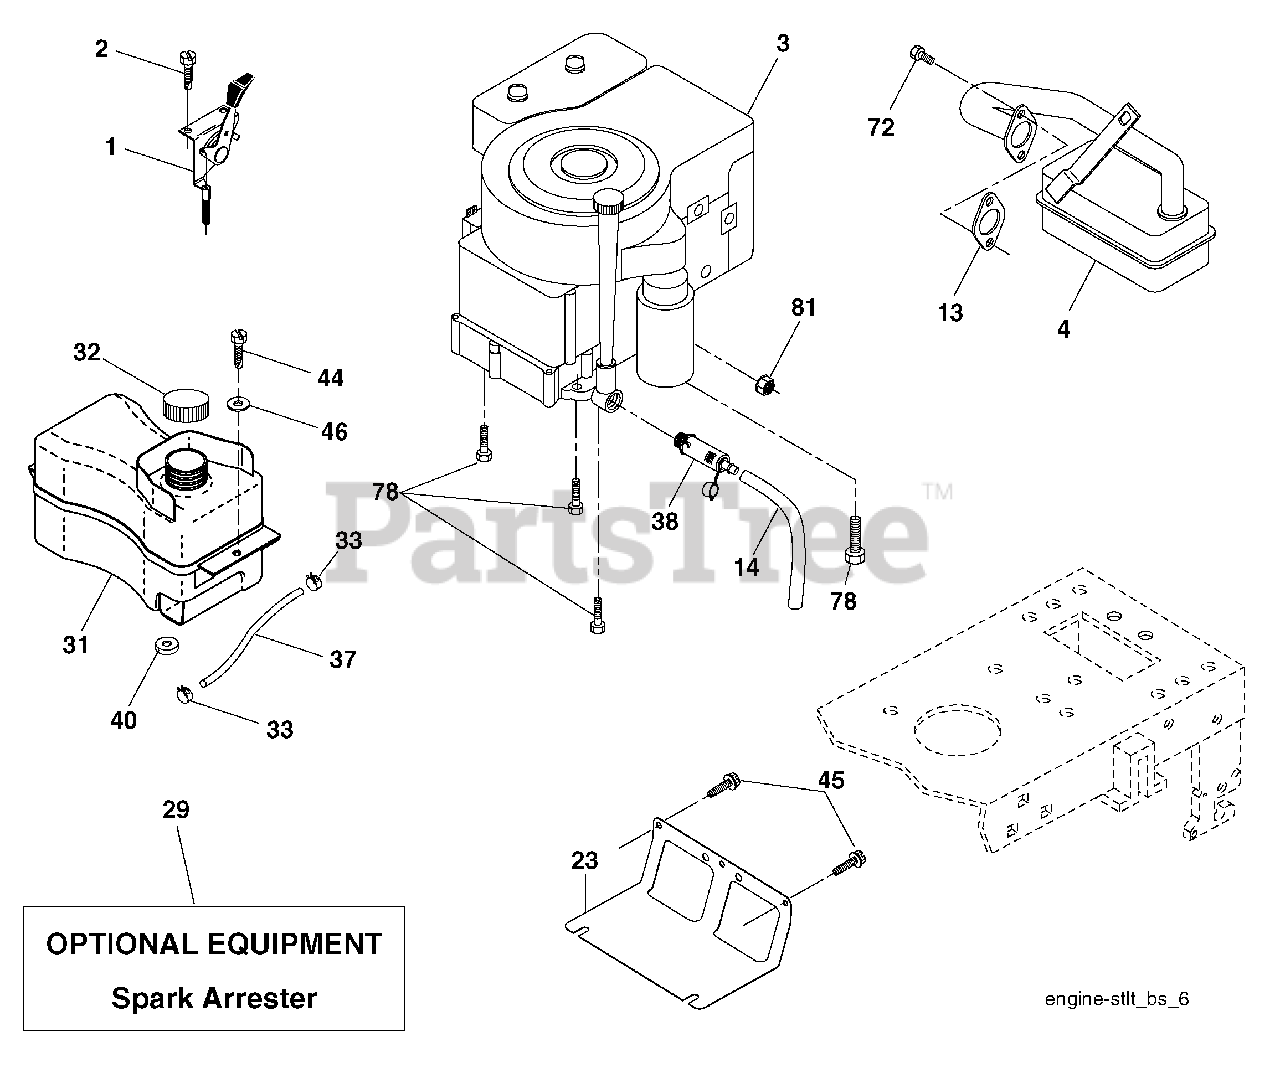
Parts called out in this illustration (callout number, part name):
1	Control Th/ch Flag
2	Screw Hex Thd Cut 1/4-20 x 1/2
4	Muffler Exhaust B&S
13	Gasket Eng 1 313 Id Tin Plated
14	Tube Drain Oileasy
23	Shield BRN/DBR Guard
29	Kit Spark Arrester (Flat Scrn)
31	Tank Fuel Front
32	Cap Asm Fuel
33	Clamp Hose
37	Line Fuel 20"
38	Plug Drain Oil
40	Bushing Snap Nyl Blk Fuel Line
44	Screw Thdrol 1/4-20 x 3/4
45	Screw Hex Wsh Thdrol 3/8-16
46	Washer 9/32 x 7/8 x 16 Ga.
72	Screw Socket Hd 5/16-18 x .75
78	Screw 3/8-16 x 1-1/4
81	Nut Keps Hex 1/4-20 unc
